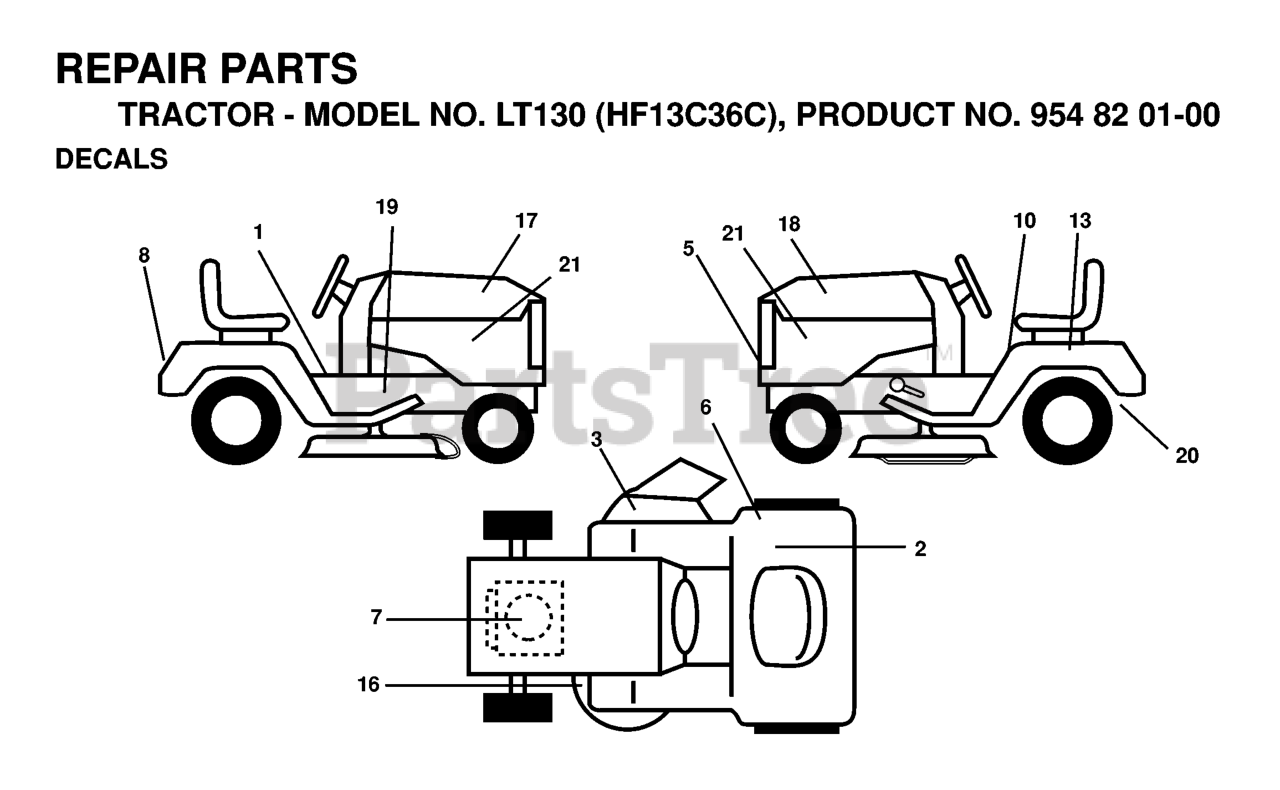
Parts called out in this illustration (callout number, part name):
1	Decal, Brake/Clutch Symbols
2	DECAL CERTIFICATION
3	DECAL MOWER CUT/FINGER
5	DECAL.GRILLE.HUSQ
6	DECAL EUROPE STANDARD CE
8	DECAL FENDER HUSQ
10	DECAL READ OWNER'S MAN SYMS
13	DECAL BTRY SYMBOLS
16	DECAL
19	DECAL
20	DECAL
21	DECAL PNL SIDE
